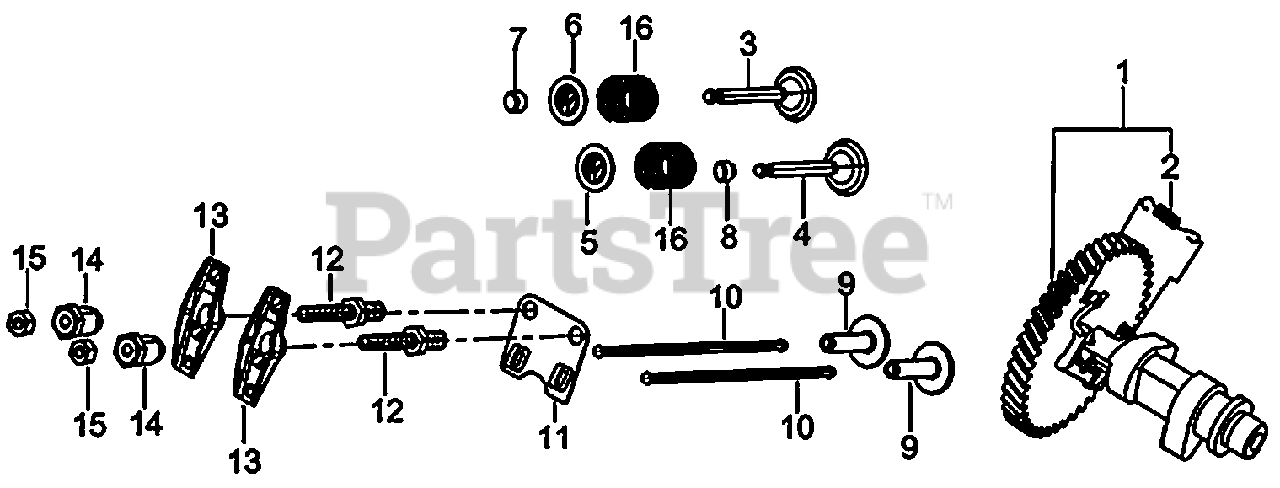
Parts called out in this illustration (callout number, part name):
1	CAMSHAFT ASSY.
3	VALVE, EXHAUST
4	VALVE, INTAKE
5	SEAT, VALVE SPRING
6	RETAINER EXHAUST VALVE
7	R0TATOR, VALVE
8	GUIDE, SEAL
9	TAPPET, VALVE
11	PLATE, GUIDE
12	BOLT, VALVE ADJUSTING
13	ROCKER, VALVE
14	NUT VALVE ADJUSTING
15	NUT, VALVE LOCK
16	SPRING, VALVE
